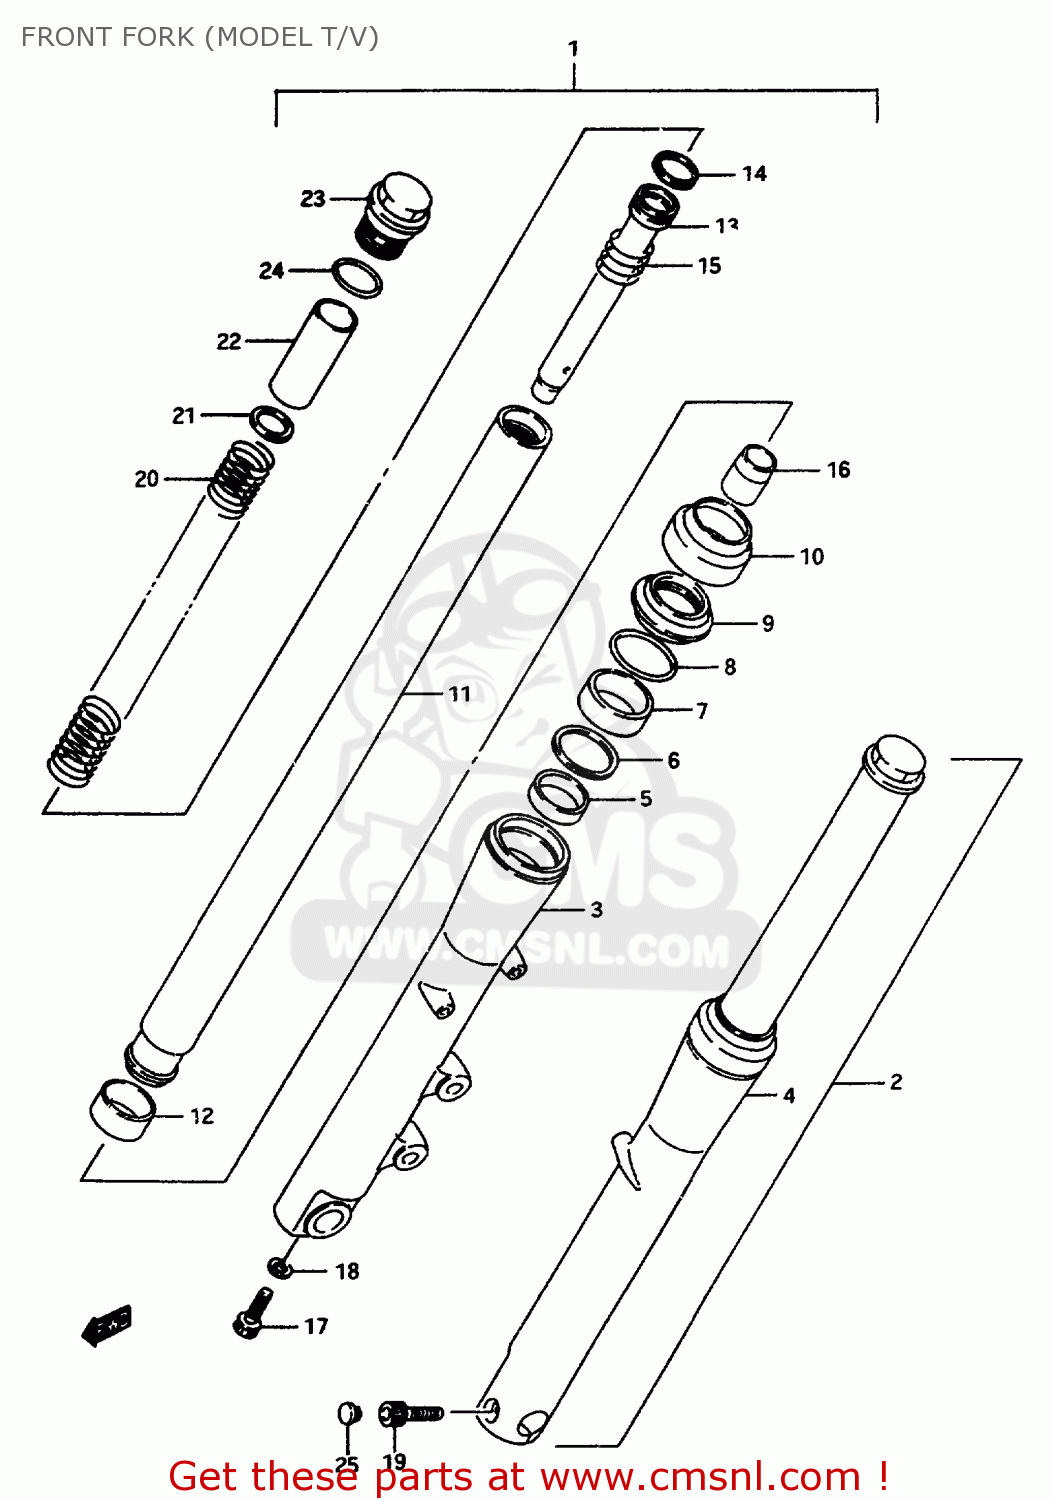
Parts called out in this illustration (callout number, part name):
1	DAMPER ASSY,FR FORK,R
2	DAMPER ASSY,FR FORK,L
3	TUBE,OUTER,R
4	TUBE,OUTER,L
5	BUSH,GUIDE
6	SPACER,SEAL
7	SEAL,OIL
8	RING,OIL SEAL STOPPER
9	SEAL,DUST
10	COVER,CASE
11	TUBE,INNER
12	BUSH,SLIDE
13	PIPE,SEAT
14	RING,PISTON
15	SPRING,REBOUND
16	PIECE,OIL LOCK
17	BOLT(8X27)
18	GASKET (NAS)
19	BOLT
20	SPRING
21	WASHER,SPRING
22	COLLAR,SPRING
23	BOLT,FORK
24	O RING
25	CAP(OD:14.5)
